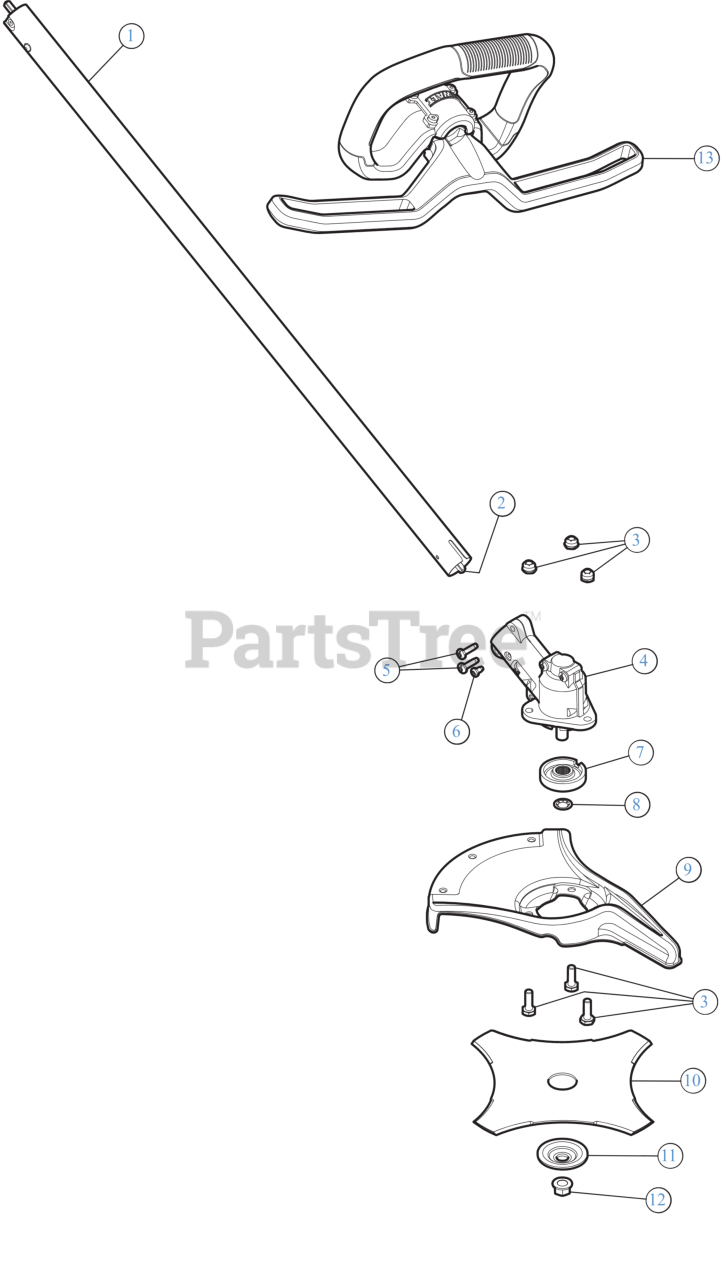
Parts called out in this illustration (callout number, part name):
1	LOWER BOOM ASSEMBLY
2	SHAFT, DRIVE
3	SCREW SET-GUARD MT
4	GEARBOX ASSEMBLY
5	SCREW #
6	SCREW, 8-32 x .312 P
7	SPACER-GEARBOX
8	PALNUT:3/8" DIAM
9	SHIELD-BLADE CAST
10	BRUSHBLADE W/COVER
11	WASHER-BLADE CLAMP BRUSH CUT
12	BLADE LOCK NUT
